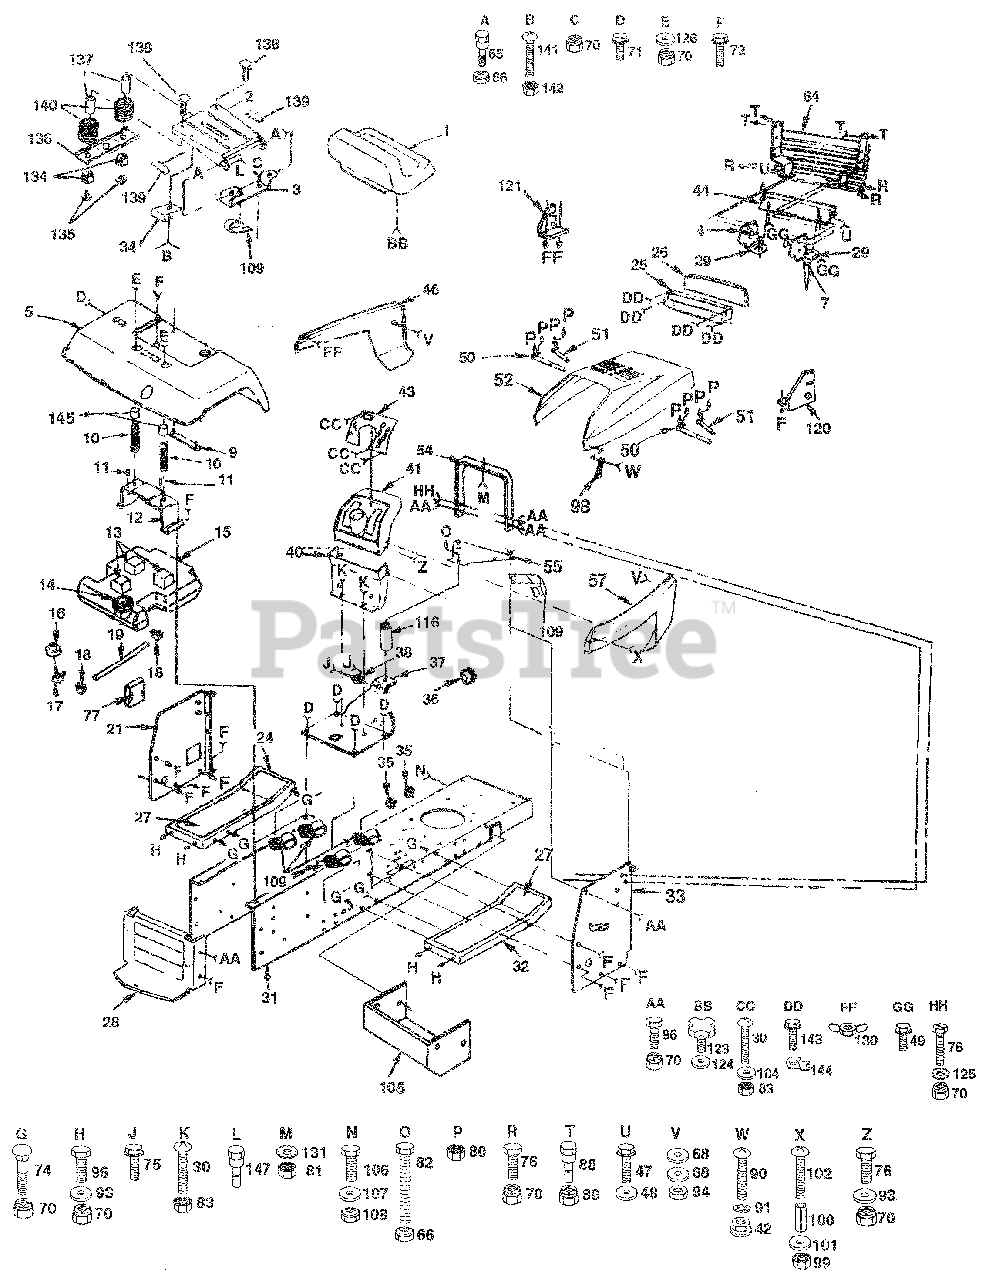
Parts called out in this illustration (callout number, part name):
2	Pan, Seat
3	Bracket, Pivot, Seat
4	Bracket, Asm. LH. Pivot
7	Bracket, Asm. R.H. Pivot
9	Strap, Fender
10	Spring, Compression.Seaf
11	Nut, Push
12	Bracket, Fender
13	Pad, Spacer
14	Gap, Fuel
15	Tank, Fuel
17	Stem, Tank, Fuel
18	Bushing
18	Clamp, Hose
19	Line, Fuel
21	Panel, Dash, L.H.
24	Footrest, L.H.
25	Bezel, Assembly
27	Pad, Footrest
28	Lens
29	Washer, 11/32 X 3/4 X 12 Ga.
30	Screw, Cr. Thd. 5/16-18 x 3/4
32	Footrest, R.H.
33	Panel, Dash, R.H.
34	Clip, Insulated
35	Bushing, Snap, Split
38	Bushing, Snap
38	Bushing, Steering
40	Dash Assembly, Lower
42	Nut, Weld
43	Plate, Dash
44	Strap, Grill
46	Panel, Side, L.H.
47	Screw, Hex Wsh. Thd. Cut 1/4-20 X 3/4
48	Washer 9/32 X 5/8 X 16 Ga.
49	Screw, Hex Wsh Thdrol 5/16-18 X 3/4
50	Strap Assembly, Hinge, Rear
51	Strap Assembly, Hinge, Front
54	Support, Dash
55	Plate, Support, Battery
57	Pane!, Side R.H.
64	Grill Assembly
68	Nut, Lock 5/16-18
68	Washer 9/32 X 3/4 X 16 Ga.
70	Nut, Crownlock 3/8-16
71	Screw, Hex Washer Thread Rolling 3/8-16 x 1/2
72	Screw, Hex Washer Thread Rolling 3/8 -16 x 3/4
74	Bolt, Carriage 3/8-16 x 3/4
75	Screw, Hex Self Tapping #10-16 x 1/2
76	Bolt, Hex 3/8-16 x 1
77	Cover, Access
80	Nut, Hex Keps
81	Nut, Hex 1/4-20
82	Bolt, Hex 5/16-18 x 2
83	Nut, Keps 5/16-18
85	Bolt, Shoulder 5/16-18
88	Bolt, Shoulder 1/4-20
89	Crownlock Nut 1/4-20
90	Screw, Pan Hd Mach. #10-24 1/2
91	Washer, Lock #10
93	Washer 13/32 x 13/16 x 12 Ga.
94	Nut, Fin Hex 1/4-20 UNO
96	Bolt, Hex 3/8 -16 x 3/4
98	Latch, Hood
99	Nut, Keps 10-24
100	Spacer, Split 10 x 3/4
101	Washer 7/32 x 1/2 x 18 Ga.
102	Screw, Mach. Cr. Pan 10-24 x 1-1/4
104	Washer 11/32 x 11/16 x 16 Ga.
105	Shield, Heat, Front
106	Bolt, Hex 1/4-20 x 3/4
107	Washer 9/32 x 7/8 x 16 Ga.
108	Nut, Self-Retaining 1/4-20
120	Bracket Assembly, R.H.
121	Bracket Assembly, L.H.
123	Adjustment Knob
124	Washer 17/32 x 1 -3/16 x 12 Ga.
125	Washer Lock 3/8 Ext. Tooth
126	Washer 13/32 x 1 x 14 Ga.
131	Washer, 1/4 Ext. Tooth
134	Bushing, Snap .80
136	Bracket, Switch Mount
137	Spacer, Split .28 x .88
138	Bolt.Carr. 1/4-20 x 1-3/8
139	Foam Strip
140	Spring, Compression
141	Screw, Pan Hd. #10-32
142	Nut, Keps #10
143	Screw, Hex WH HD Tap #10-16 X 5/8
144	J Fastener
145	Spring Cap
147	Bolt, Shoulder 5/16-18 x.62
185	Nut, Hex, Large, Flange, Lock
